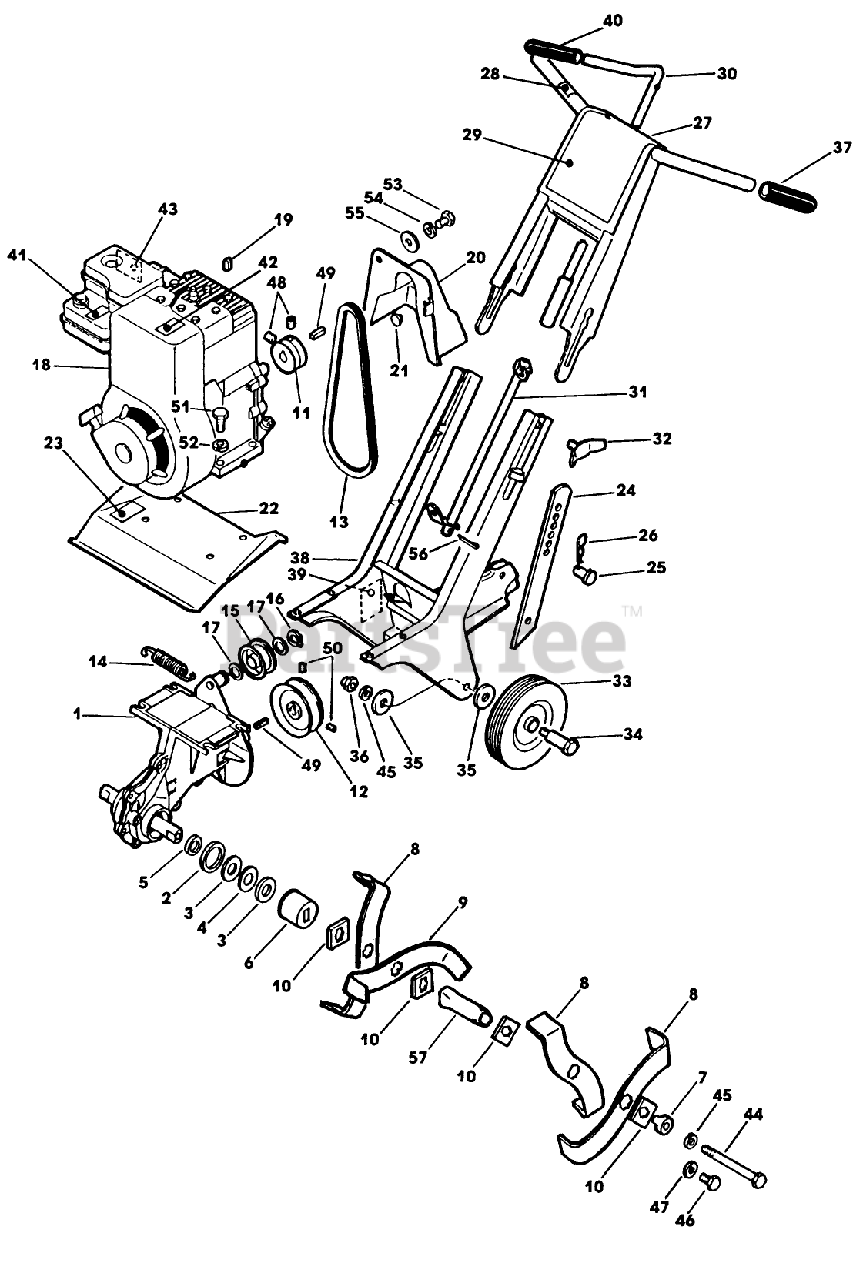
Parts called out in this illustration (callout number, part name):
2	SEAL-FELT
3	SEAL
4	WASHER
5	SEAL
13	V-BELT
17	WASHER
26	PIN - SPRING CLIP
36	NUT-LOCKING
45	WASHER
47	WASHER
50	SET SCREW
57	EXTENSION
